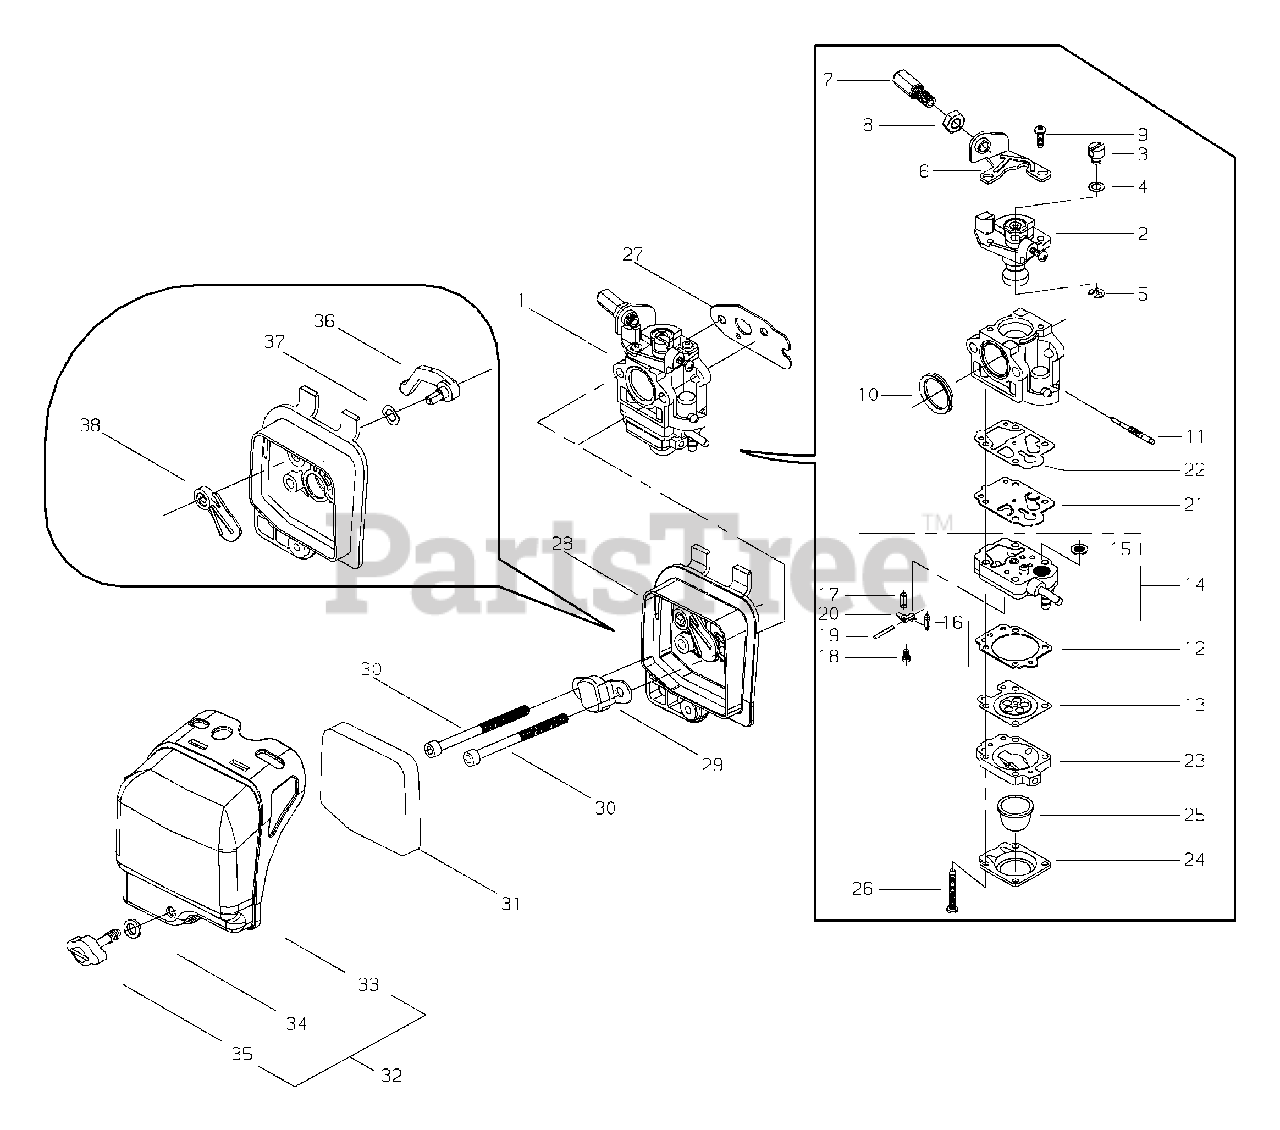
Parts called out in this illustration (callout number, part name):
1	CARBURETOR
2	THROTTLE VALVE ASSY
3	SWIVEL
4	WASHER
5	RING, RETAINING
6	BRACKET, CABLE
7	NUT, CABLE ADJUST
8	NUT
9	SCREW
10	SEAL
11	NEEDLE - HIGH SPEED
12	GASKET, METERING
13	DIAPHRAGM, METERING
14	PUMP BODY ASSY
15	STRAINER
16	VALVE, INLET NEEDLE
17	SPRING, METERING LEVER
18	SCREW, METERING LEVER PIN
19	PIN, METERING LEVER
20	LEVER, METERING
21	DIAPHRAGM, PUMP
22	GASKET, PUMP
23	BASE, PURGE
24	RETAINER, PURGE BULB
25	BULB, PURGE
26	SCREW, PUMP COVER
27	GASKET, INTAKE
28	AIR FILTER CASE ASSY
29	PLATE, PREVENT
30	SCREW - 5X60
31	FILTER, AIR
32	AIR FILTER COVER ASSY
33	COVER, AIR FILTER
34	WASHER - VINYL
35	THUMBSCREW
36	LEVER, CHOKE
37	WASHER - SPRING
38	PLATE, CHOKE
